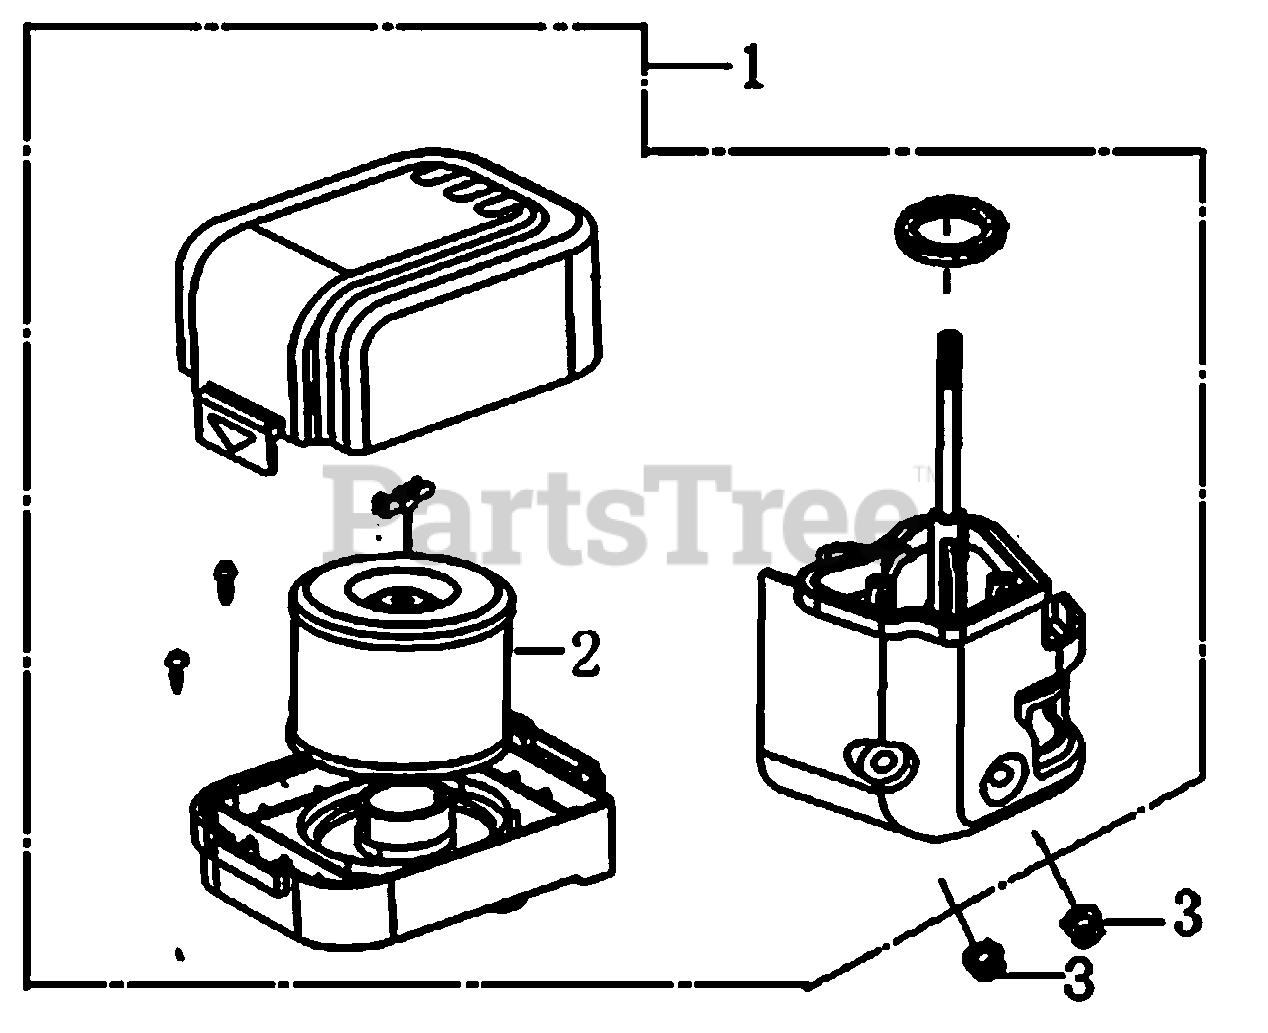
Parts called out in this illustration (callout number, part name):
1	AIR CLEANER ASSY
2	ELEMENT ASSY., AIR CLEANER
3	NUT, FLANGE, 6MM
